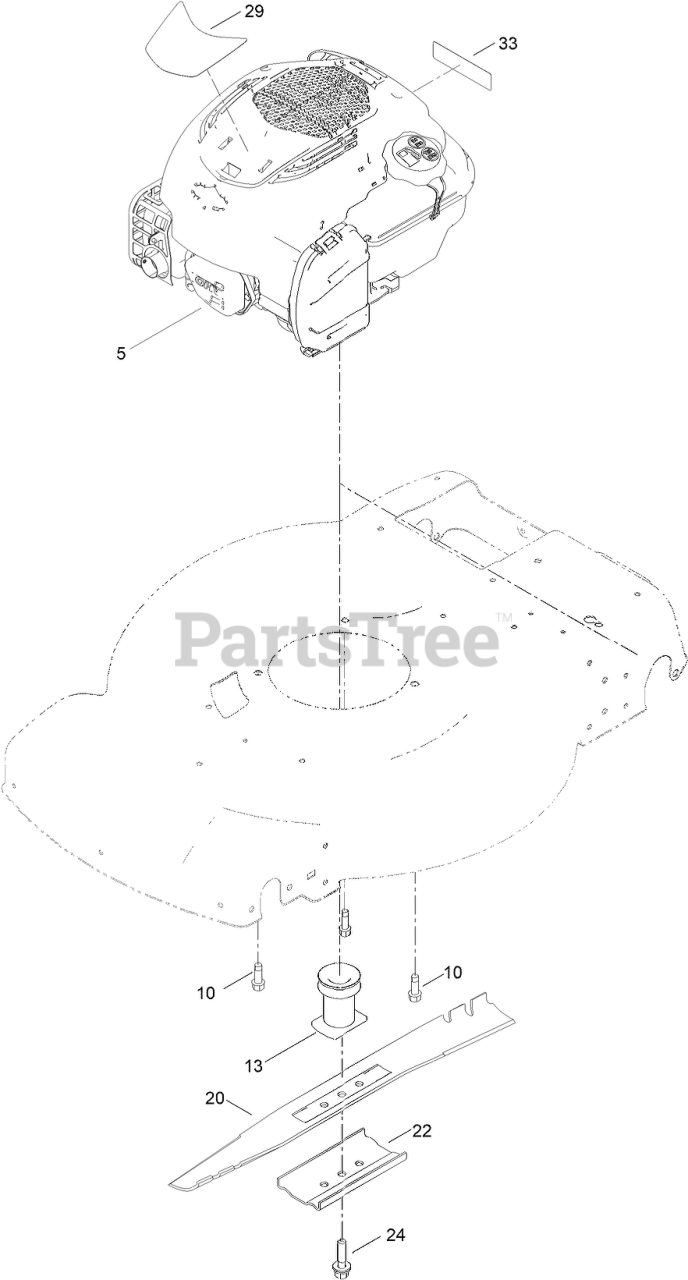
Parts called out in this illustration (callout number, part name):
5	ENGINE-BRIGGS, 625 EXI ES
10	SCREW-THD FORM, HWH
13	DRIVER-BLADE
20	BLADE-22 INCH
22	SUPPORT-BLADE
24	BOLT-BLADE
29	DECAL - BRIGGS 625 EX ES
33	DECAL-ARRESTOR, SPARK
